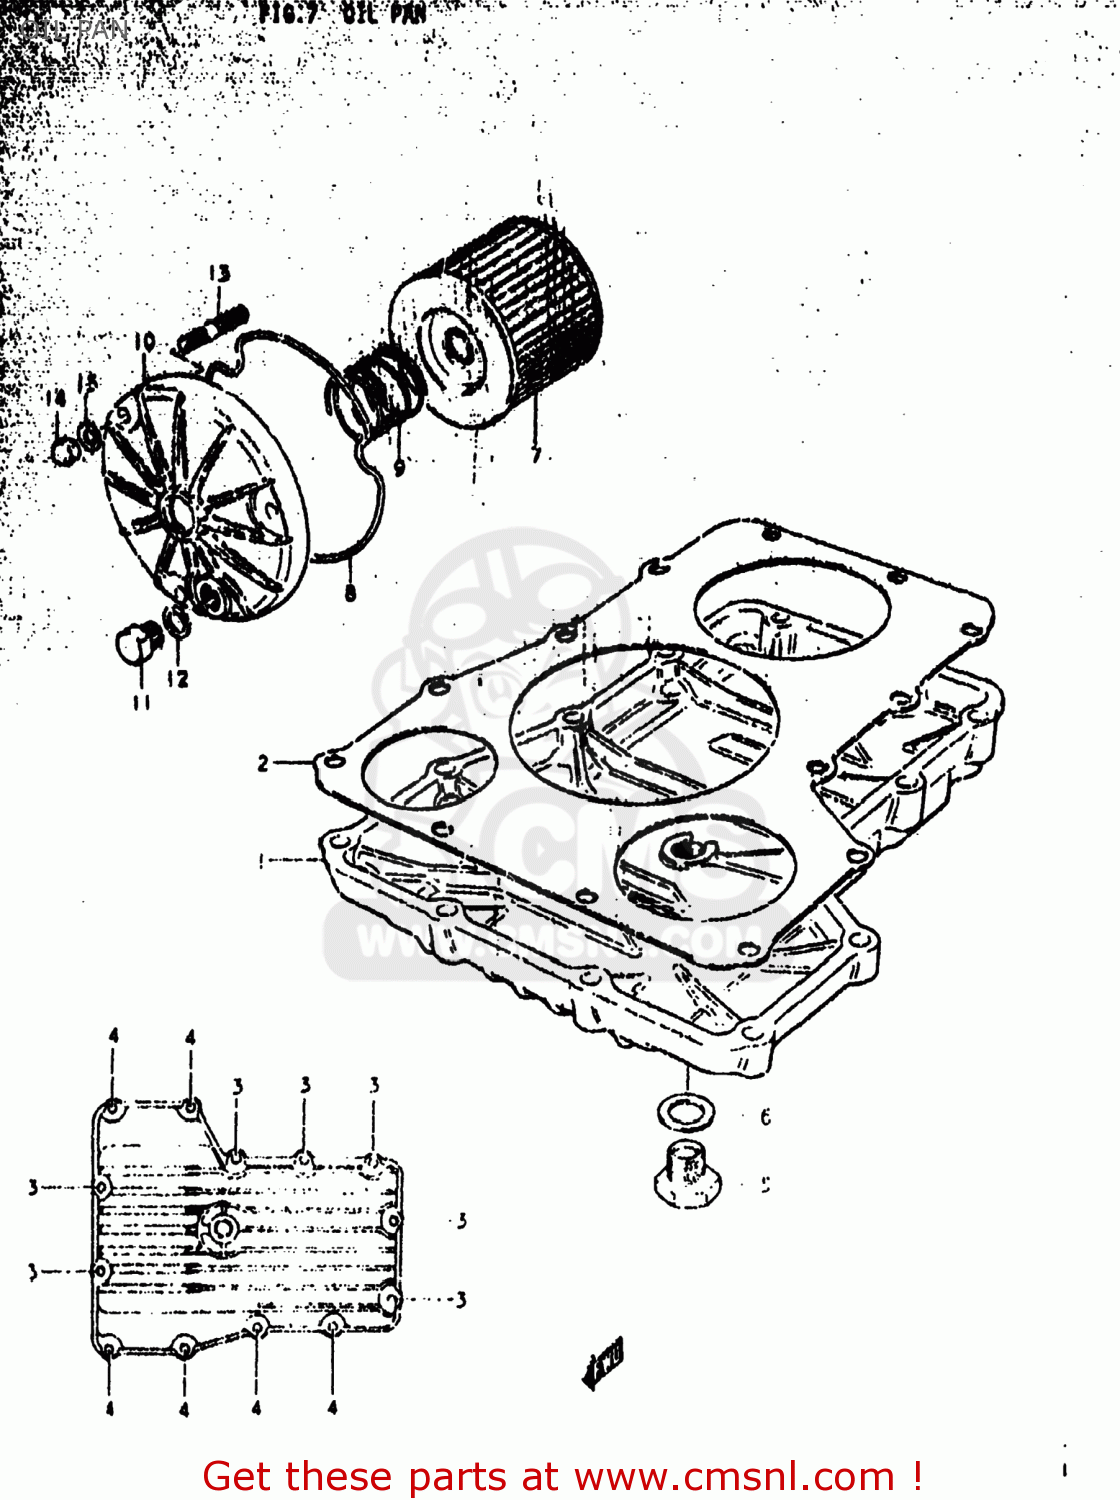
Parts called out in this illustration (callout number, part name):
1	PAN,OIL
2	GASKET,OIL PAN (MCA)
3	BOLT
4	BOLT
5	PLUG
6	GASKET(14X19.2X2) (NAS)
7	FILTER ASSY,ENGINE OIL
8	O RING,OIL FILTER CHAMBER CAP
9	SPRING
10	CAP,OIL FILTER
11	PLUG
12	GASKET(10X14X3.6) (NAS)
13	STUD 6X20
14	NUT
15	WASHER
